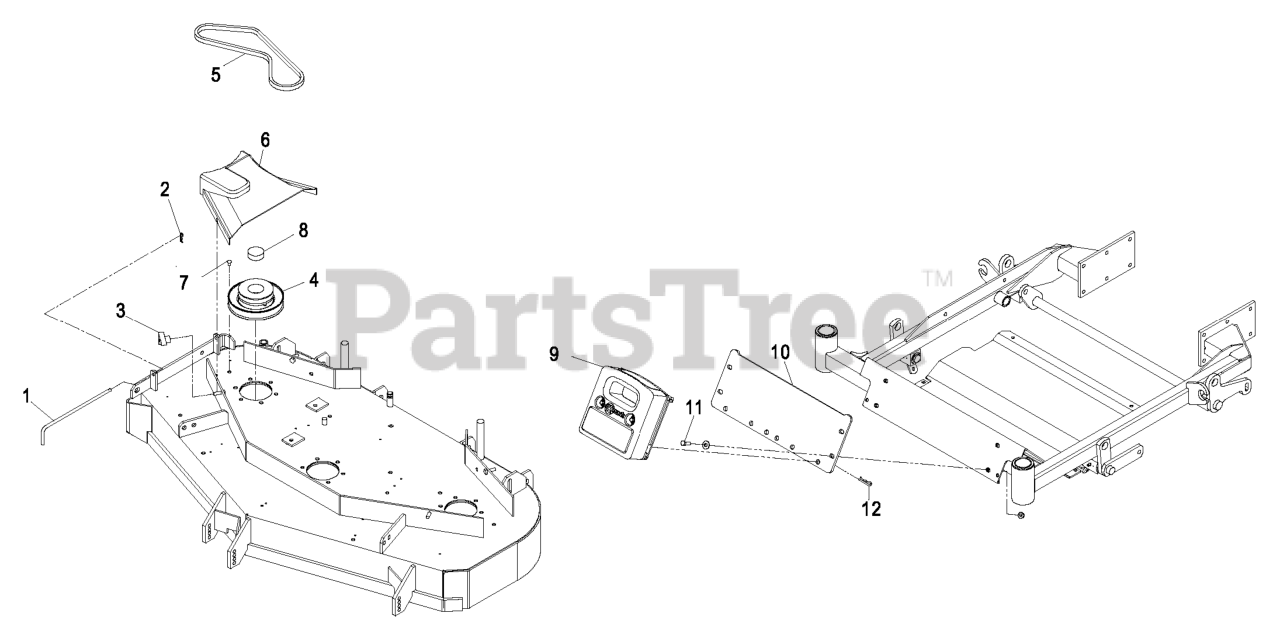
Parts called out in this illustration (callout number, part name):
1	PIN, CHUTE PIVOT PLTD
2	PIN-COTTER
3	KNOB-3 PRONG
4	SHEAVE, BLOWER DRIVE 52"
5	BELT, BLOWER 52"DECK
6	COVER, BELT 52
7	SCREW-HH
8	PLUG, BLACK NYLON 1.75
9	ASM,CAST WEIGHT
10	PLATE,WEIGHT ASM MOUNT
11	SCREW-HH
12	PIN-HAIR
